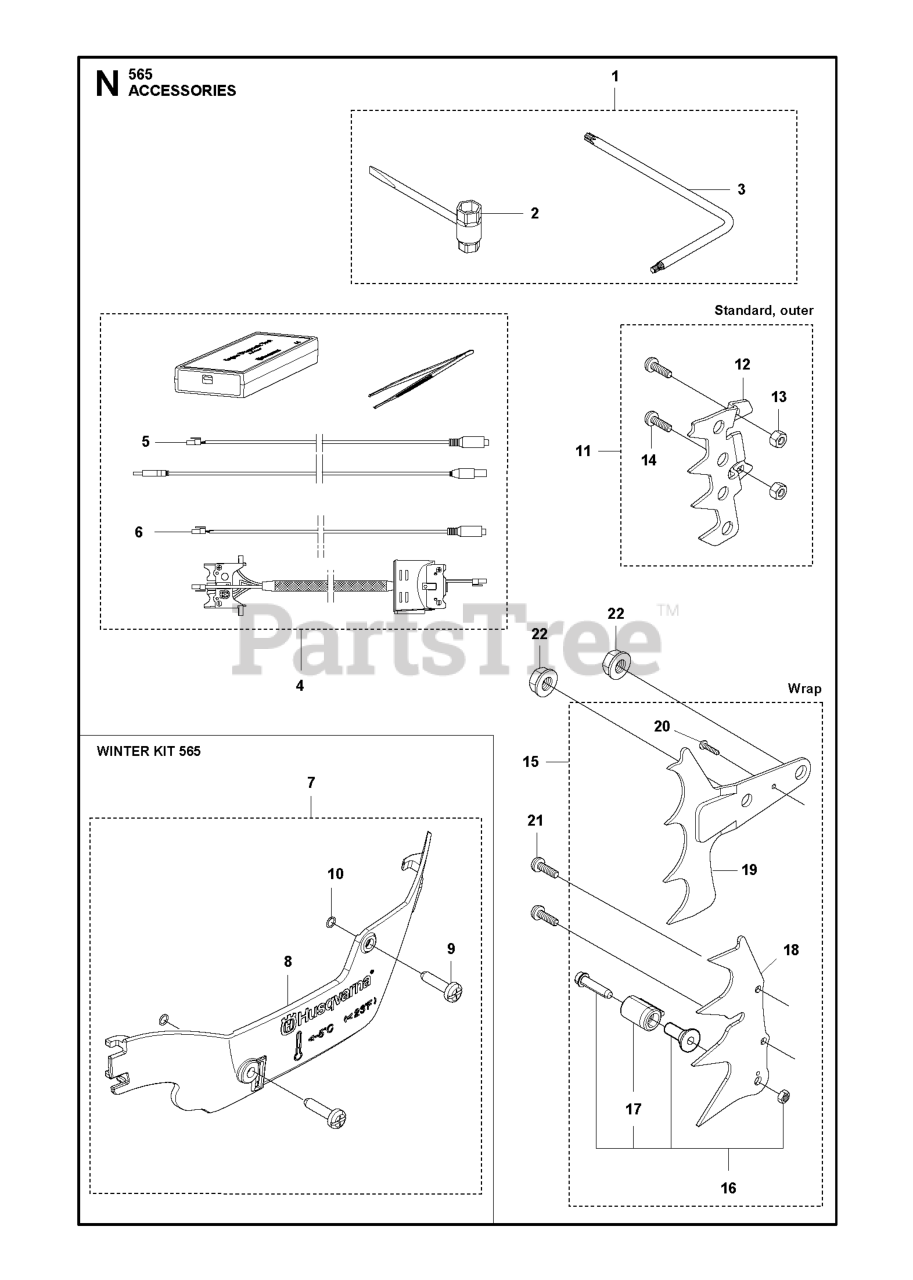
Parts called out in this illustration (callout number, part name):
2	COMBI TOOL
4	DIAGNOSTIC TOOL KIT
5	CABLE ASSY
6	CABLE ASSY
7	WINTER KIT
8	WINTER COVER
11	SPIKE KIT - OUTER STD H565/H57
12	SPIKE OUTER H565/H572
14	SCREW ITXSCFM
15	SPIKE KIT WESTCOAST H565/H572
16	CHAIN CATCHER H565/H572 KIT
18	FELLING DOG
19	FELLING DOG
20	SCREW CITXPANT
21	SCREW ITXSCM
22	NUT M8 FLANGE
